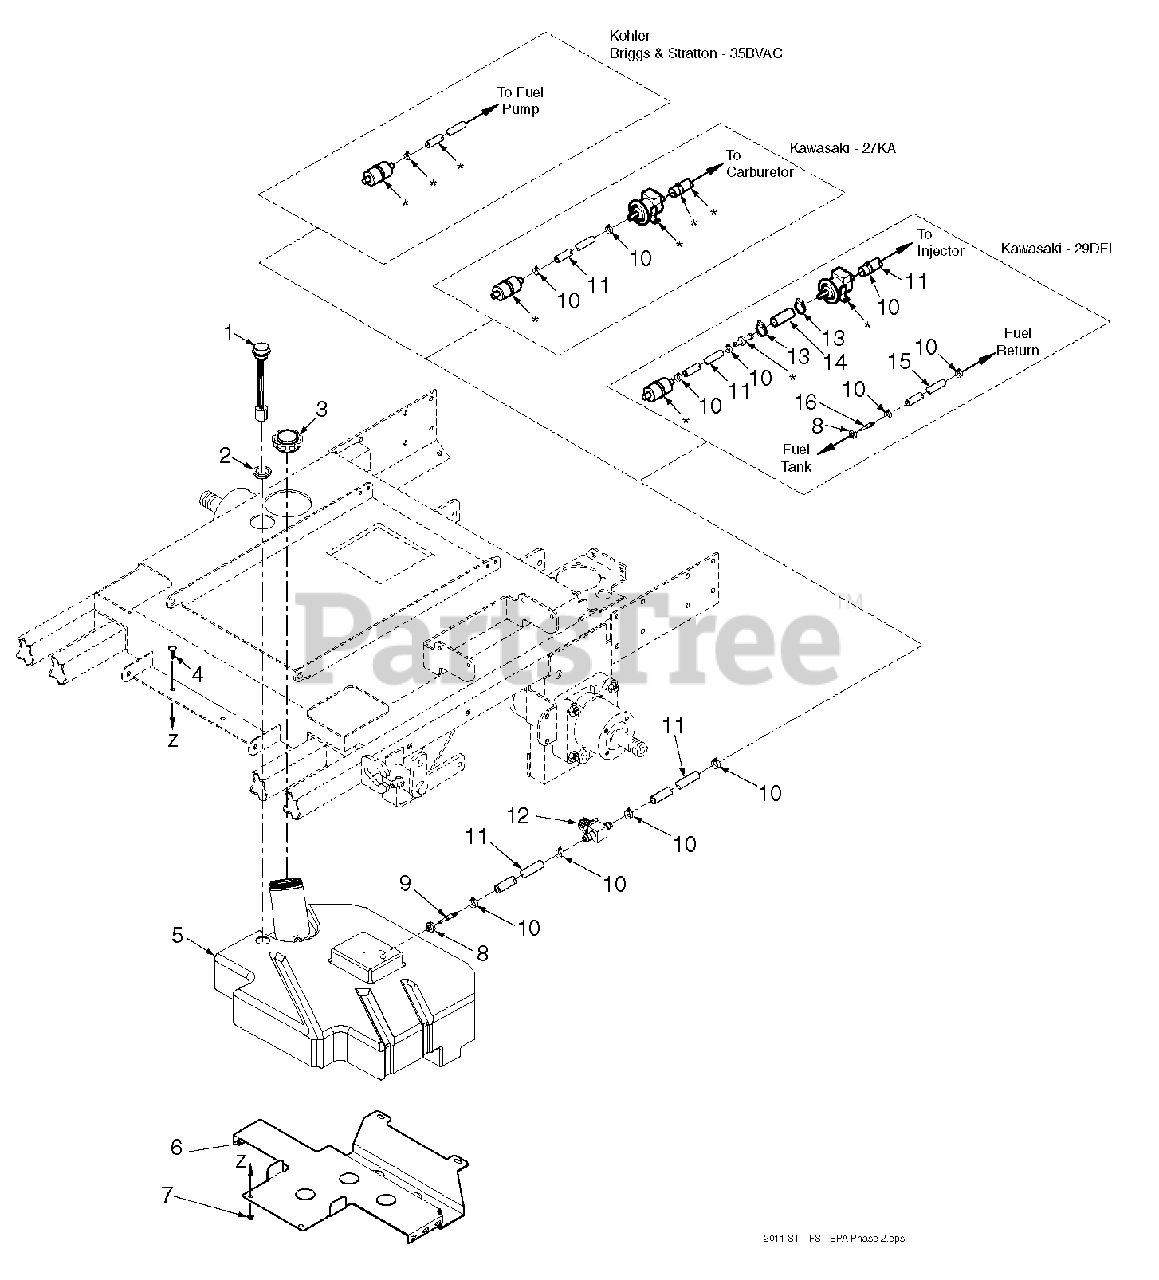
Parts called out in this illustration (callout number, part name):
1	Fuel Gauge Assembly
2	Seal, Fuel Gauge
3	Fuel Cap
4	Bolt, Carriage 1/4-20 x 3/4"
5	Fuel Tank Assembly - STT
5	Fuel Tank Assembly - STT-29DFI
6	Support Bracket, Fuel Tank
7	Nut, 1/4-20 Serrated Flange
8	Bushing, .56 Dia. Viton
9	Hose Fitting
10	Clamp, Fuel Hose 1/4" I.D.
10	Clamp, Fuel Hose 5/16" I.D.
11	Fuel Hose, 1/4" I.D. Non-Perm
11	Fuel Hose, 5/16" I.D. Non-Perm
12	Valve, Fuel Shut-Off
13	Clamp, .87" Max. Dia
14	Fuel Hose, 1/2" I.D. Non-Perm
15	Fuel Hose, 1/4" I.D. Non-Perm
16	Return Fitting, Straight
